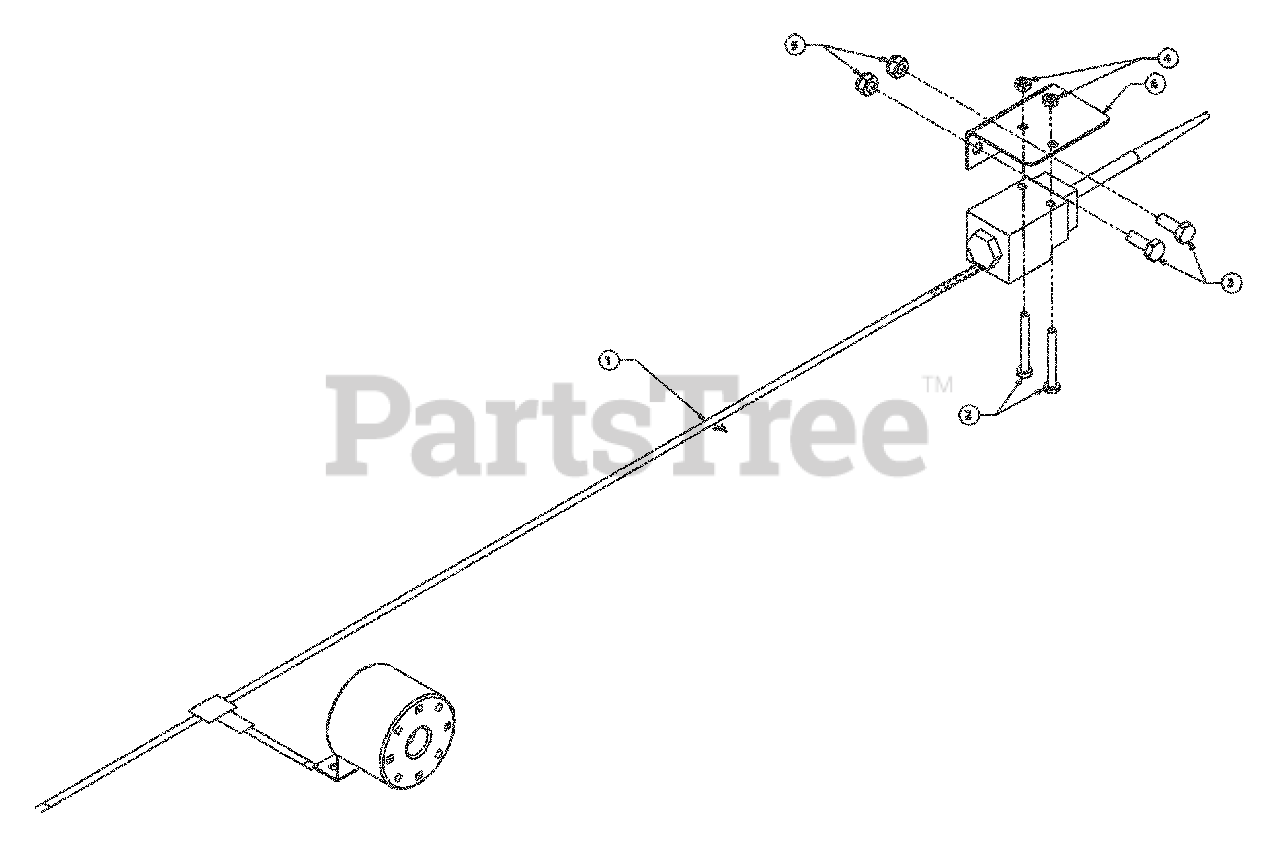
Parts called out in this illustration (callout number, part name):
1	HARN ASM:500:BAG FULL
2	SCR:M4-.5:35.00 LG DIN 7985
3	SCR:M6-1:16.00 LG DIN 933
4	NUT:HEX:M4:DIN 985
5	NUT:HEXLK:M6-1:NYLON DIN 985
6	BRKT:SW:BAG FULL
